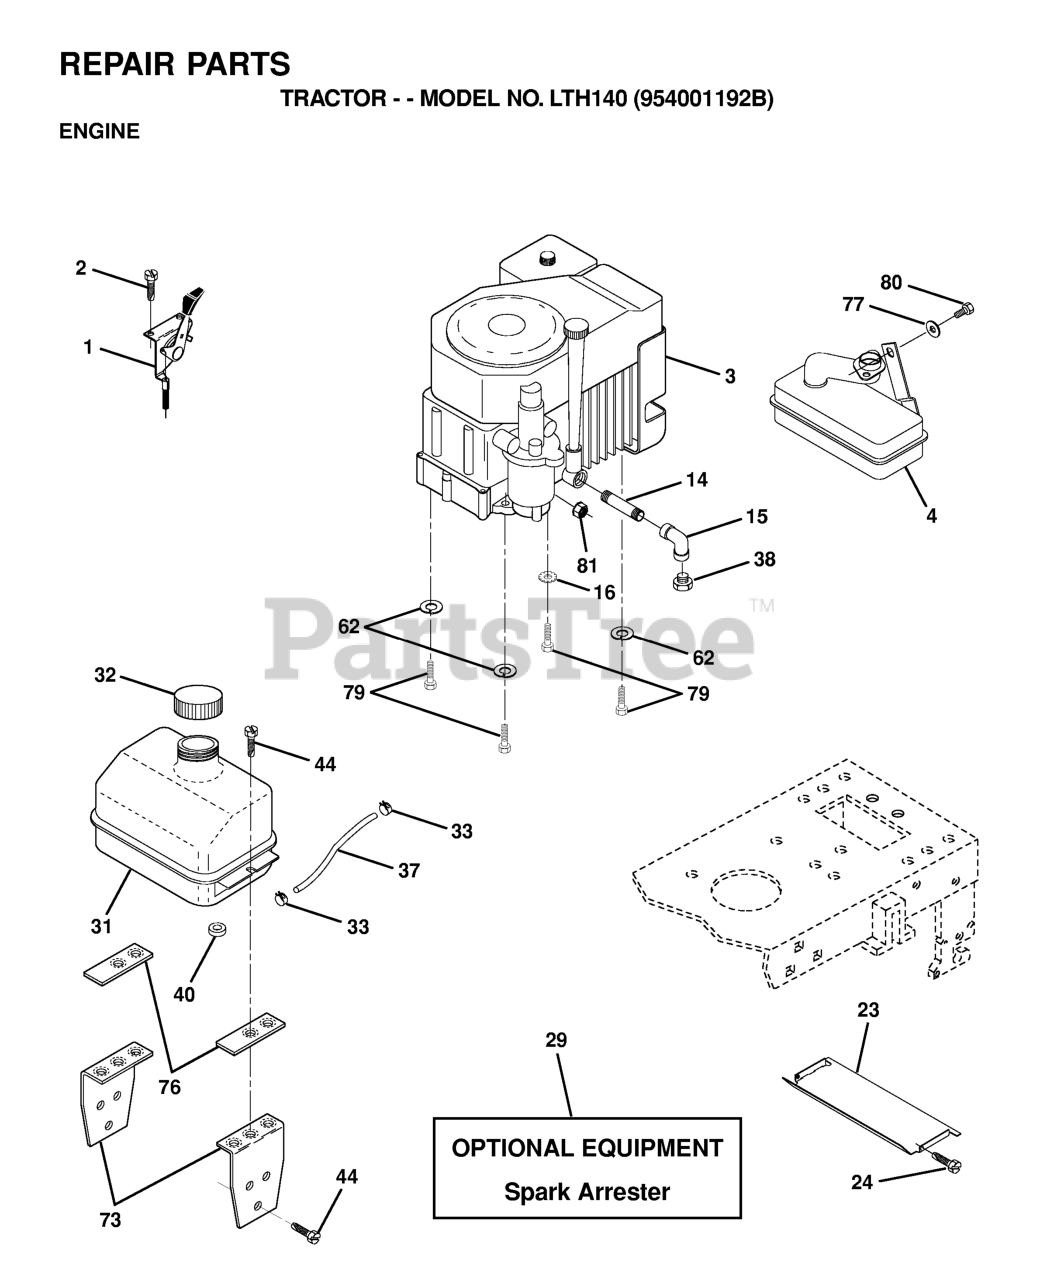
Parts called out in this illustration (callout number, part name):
1	THROTTLE CONTROL
2	SCREW LT
4	MUFFLER LT 12.5
14	Std. Pipe Nipple 3/8 - 18 NPT x 3 1/2
15	ELBOW
16	LOCKWASHER
23	HEAT SHIELD
29	KIT.SPARK ARRESTOR 794945 B&S
31	TANK FUEL LT
32	FUEL CAP
33	HOSE CLAMP
37	FUEL LINE T
40	SNAP BUSHING T
44	SCREW
62	WASHER.LOCK.HVY.HLCL.SPR.5/16
73	BRACKET FUEL TANK T
76	CLAMP, FUEL TANK T
77	WASHER
79	BOLT, HEX
80	Bolt, Hex Head, Fin. 5/16-18 x 1/2
81	NUT
